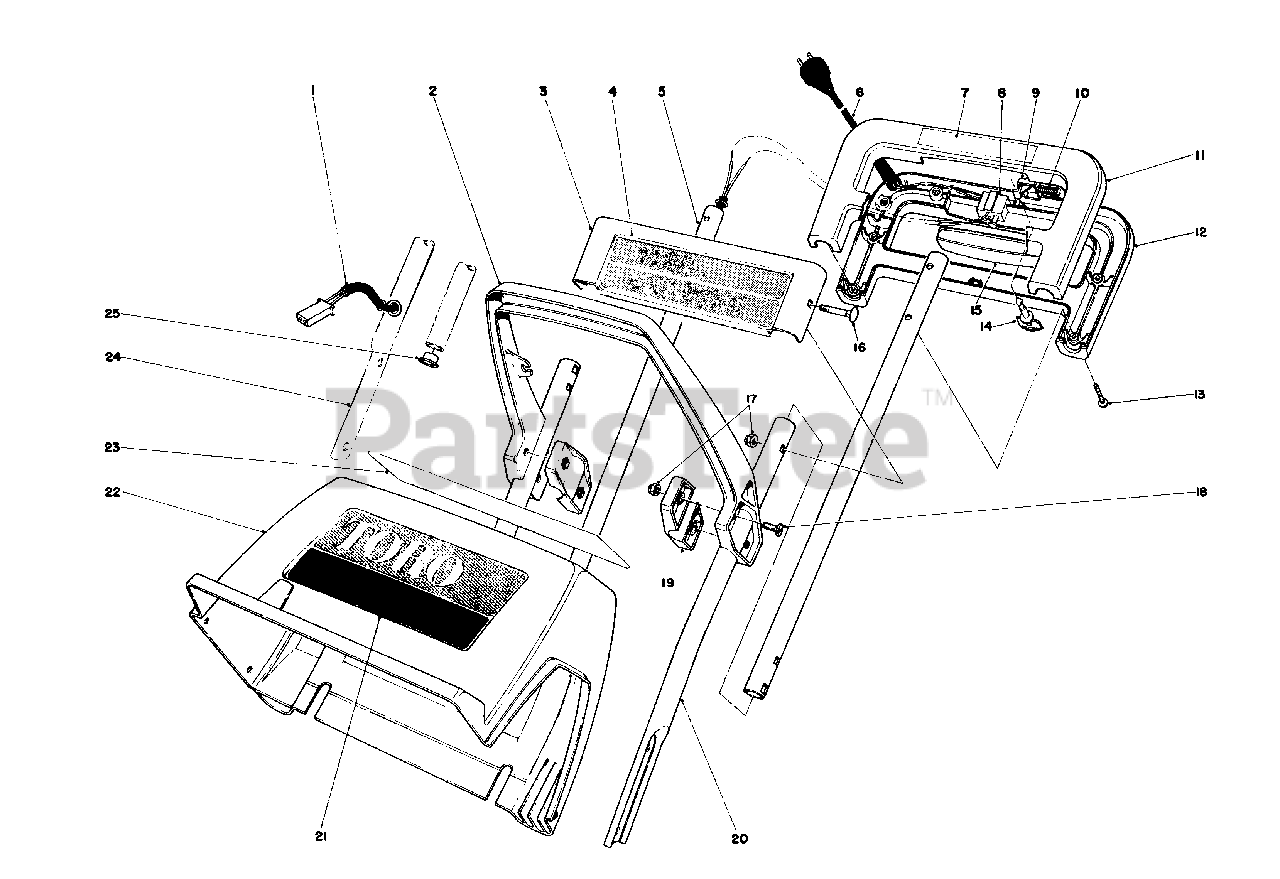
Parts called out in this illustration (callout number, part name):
1	Wire Harness
2	Middle Handle
3	Escutcheon Plate
4	Decal-Electric
5	Upper Tube
6	Cord Supply
7	Decal-Handle
9	Lockout-Switch
10	Spring Compression
11	Handle-Upper Control
12	Handle-Lower Control
13	Screw
15	Switch Bar
16	Carriage Bolt
18	Screw-Round Head
19	Clamp-Middle Handle
20	Handle-Lower L.H.
21	Decal-Toro S-120
22	Shroud-S-120
23	Decal-U.L.
24	Handle-Lower R.H.
25	Snap Bushing
